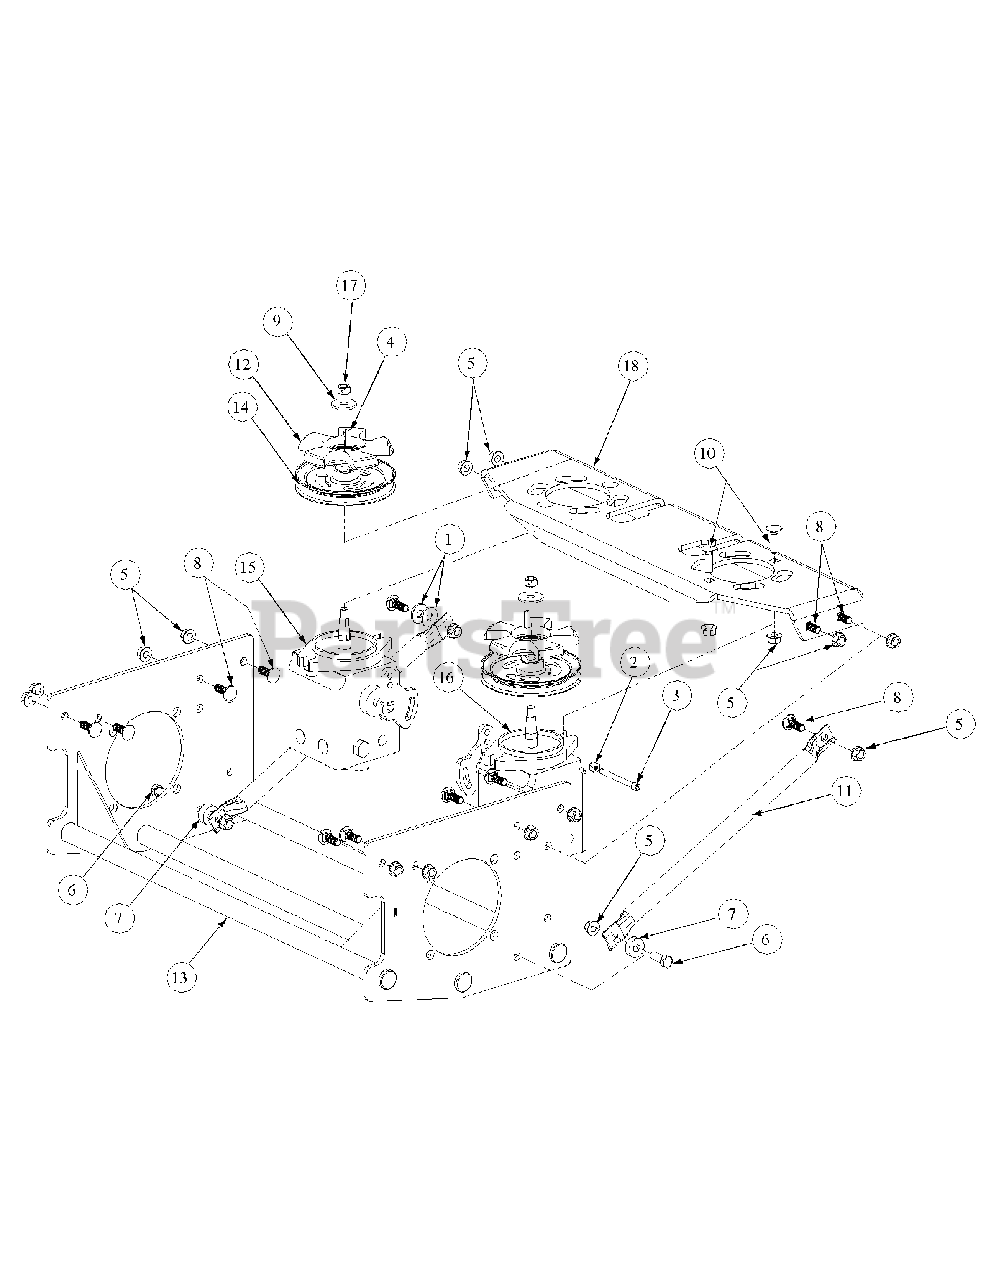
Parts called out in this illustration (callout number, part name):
1	Washer lock 3/8 zinc
2	Lock Nut, Nylon Insert, 1/4-20
3	Socket Head Cap Screw, 1/4-20 x 2-1/2
4	Key, 3/16" x 7/8"
5	Flange Lock Hex Nut, 3/8-16
6	Hex Cap Screw, 2/8 -16 x 1.25
7	Spacer, .406 ID x 1.00 OD x .38
8	Carriage Bolt, 3/8-16 x 1
9	Flat Washer, .411 x 1.25 x .100
10	Carriage Screw, 3/8-16 x 1.25
12	Hydro Pulley Fan
13	Hydro Motor Frame Assembly
14	Hydro Pulley Pump
15	Hydro Pump, LH
16	Hydro Pump, RH
17	Hex Nut, 3/8-24
18	Hydro Pump Mounting Weldment
